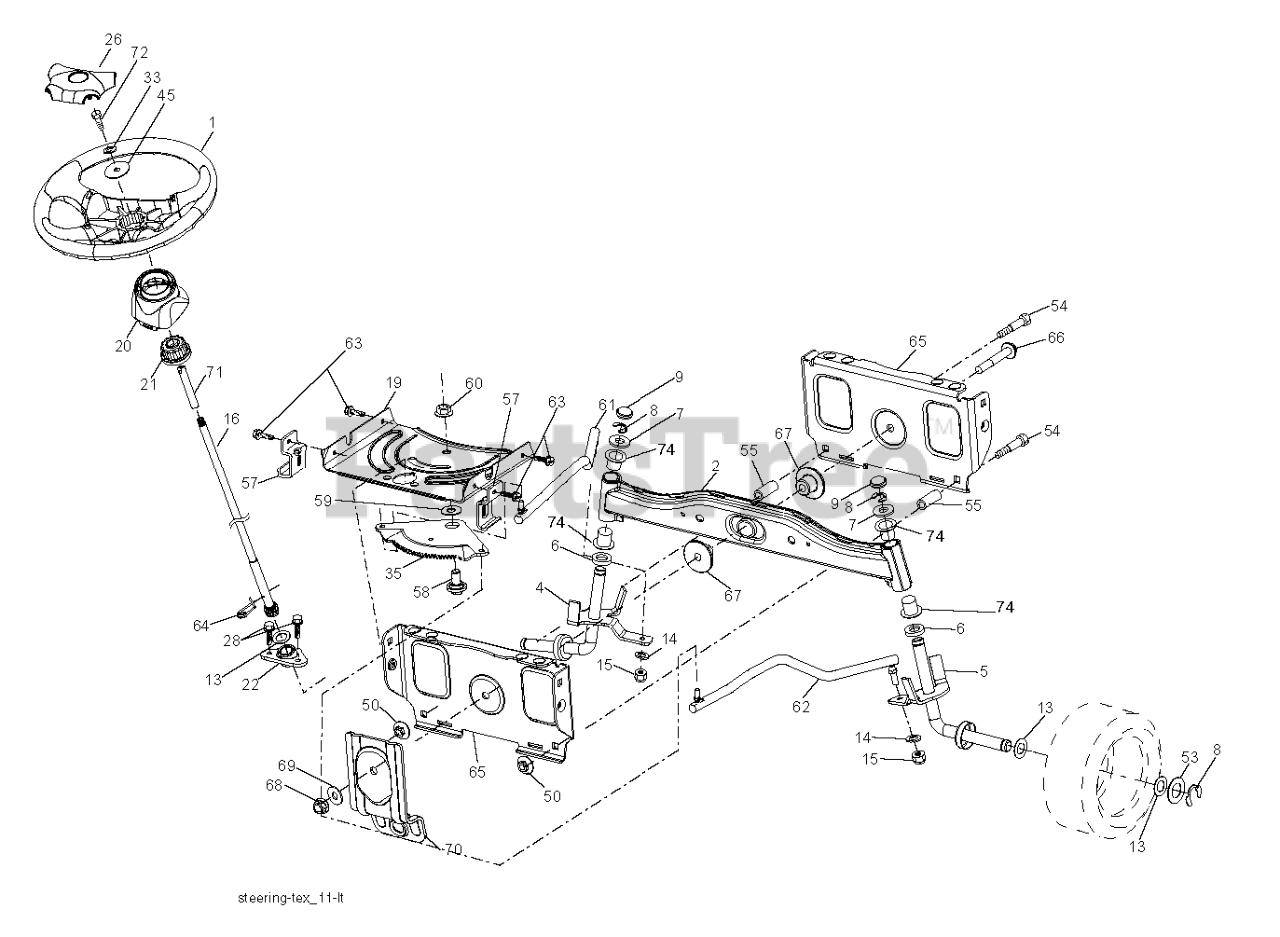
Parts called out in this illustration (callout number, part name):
1	WHEEL.STEERING.LEGEND2.GRY
2	AXLE.HALF.ASM.WELDED
4	SPINDLE.WELDED.LH.15"TEX
5	SPINDLE.WELDED.RH.15"T
6	THRUST WASHER
9	CAP.SPINDLE.BLACK
14	WASHER, LOCK 3/8
15	NUT CROWNLOCK 3/8-24
16	SHAFT STEERING
19	PLATE.STEER.DDL.NLT/NG
20	BOOT, STEERING
21	ADAPTER, WHEEL STNG..
22	BUSHING.ASM.STEERING.A
26	INSERT.CAP.STRG.WH.GRAY
28	SCREW, 3/8-16X3/4
33	WASHER.LOCK.HVY.HLCL.SPR.5/16
35	GEAR.SECTOR.PLATE.DDL.
45	WASHER.11/32
50	NUT LOCK FLG 3/8-16 UNC
53	WASHER.HARDENED
55	SPACER.BRACE.AXLE (2 2)
57	BRACKET.UPSTOP.TEX
58	BOLT.SHOULDER.SECTOR.P
59	WASHER.THURST.SECTOR.S
60	NUT FLANGE LOCK 5/8-11
61	DRAGLINK.LH.BALLSTUD.D
62	DRAGLINK.RH.BALLSTUD.D
63	SCREW
64	RETAINER.CLIP.SPRING.S
65	BRACE.AXLE.FRONT.NLT/N
66	BOLT HEX FGHD 7/16-14 X 3 SERR
67	BUSHING.PM.FRONT AXLE
68	NUT.LOCK.FLANGE.7/16
69	WASHER.1.5X.505X.118
70	BRKT.DECK.SUSPENSION.F
71	SHAFT EXTENSION STEERING
72	BOLT YT
74	BRNG T
